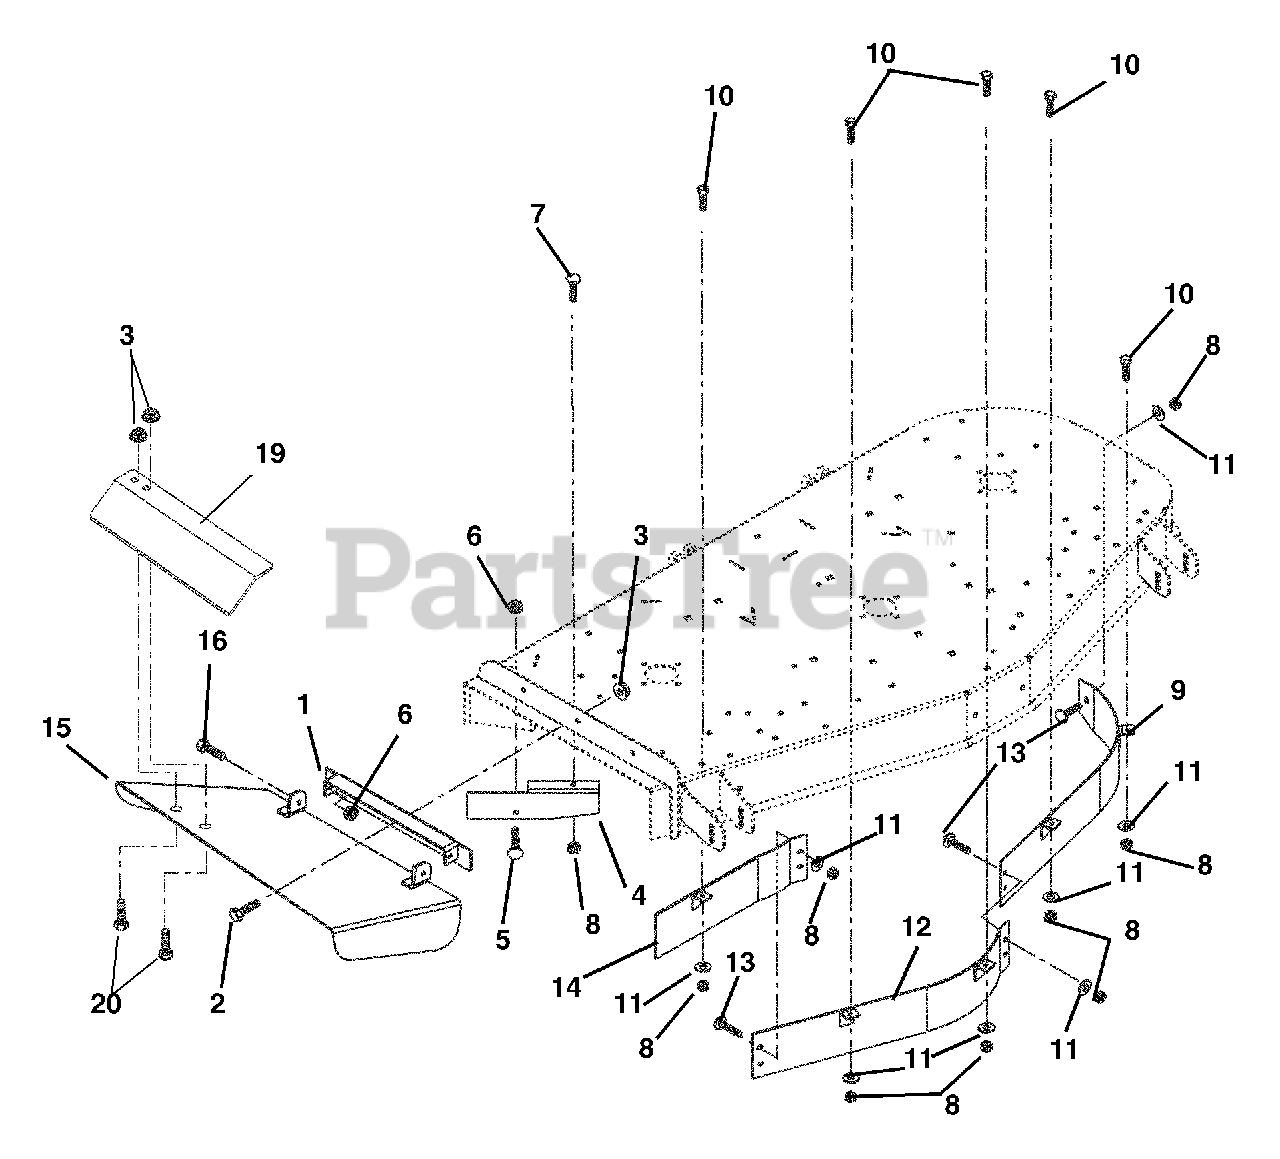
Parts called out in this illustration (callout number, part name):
1	Weldment, Discharge Chute Bracket
2	Bolt-Hex .38-16 x 1.00 Grade 5
3	Nut-Locking-Flange .38-16
4	Deflector, 60
5	Bolt-Round Head Square Neck .38-16 x 1.00 Grade 2
6	Nut-Locking-Center .38-16
7	Bolt-Round Head Square Neck .31-18 x 1.00 Grade 5
8	Nut-Locking-Nylon .31-18
9	Weldment, 60" Left Hand Baffle-Upper
10	Bolt-Hex .31-18 x 1.00 Grade 5
11	Washer-Flat-Steel .312 x .734 x .065
12	Weldment, 60" Center Baffle-Up
13	Bolt-Round Head Square Neck .31-18 x .75 Grade 5
14	Weldment, 60" Right Hand Baffle-Upper
15	Weldment, Discharge Chute 60"
16	Bolt-Hex .38-16 x 1.00 Grade 5
17	60" Discharge Cover
18	60" Mulch Kit
19	Deflector, Discharge Chute (309)
20	Bolt-Round Head Square Neck .38-16 x .75 Grade 5 (309)
